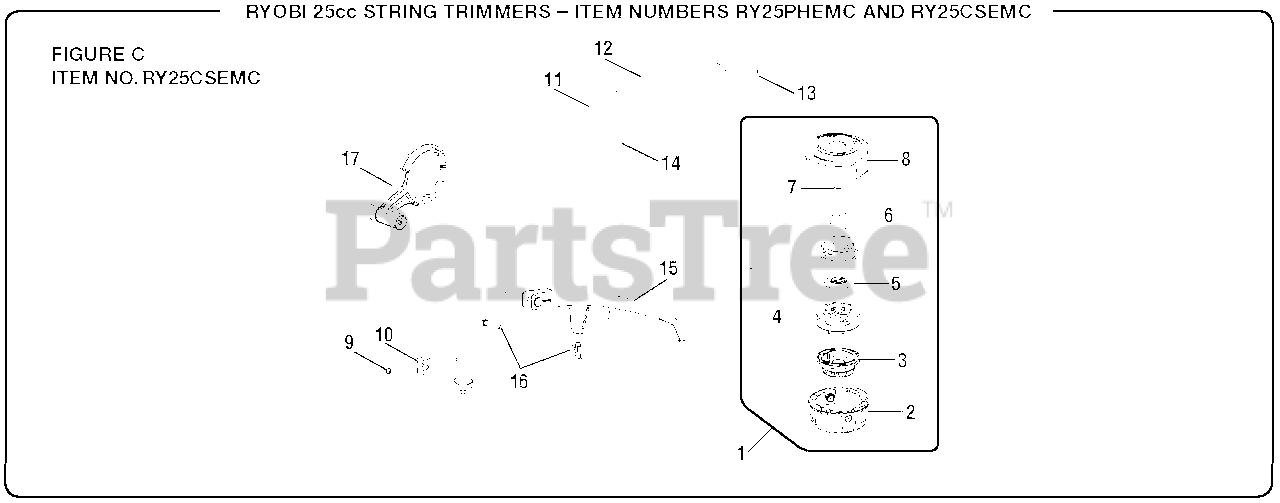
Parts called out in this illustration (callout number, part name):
1	Trimmer Head Assembly (.095)
2	Lower Housing
3	Bump Knob (Green)
5	String Guide
6	Compression Spring
7	Hex Nut (M8)
8	Upper Housing
9	Screw (#10-32 x 3/8 in., Hex Washer Hd. S.T.)
11	Expand-it Label
12	Warning Icon Label
13	Storage Hanger Cap
14	Curved Shaft Assembly
15	Grass Deflector Assembly
16	Fastener Kit
17	Crank Handle Assembly
